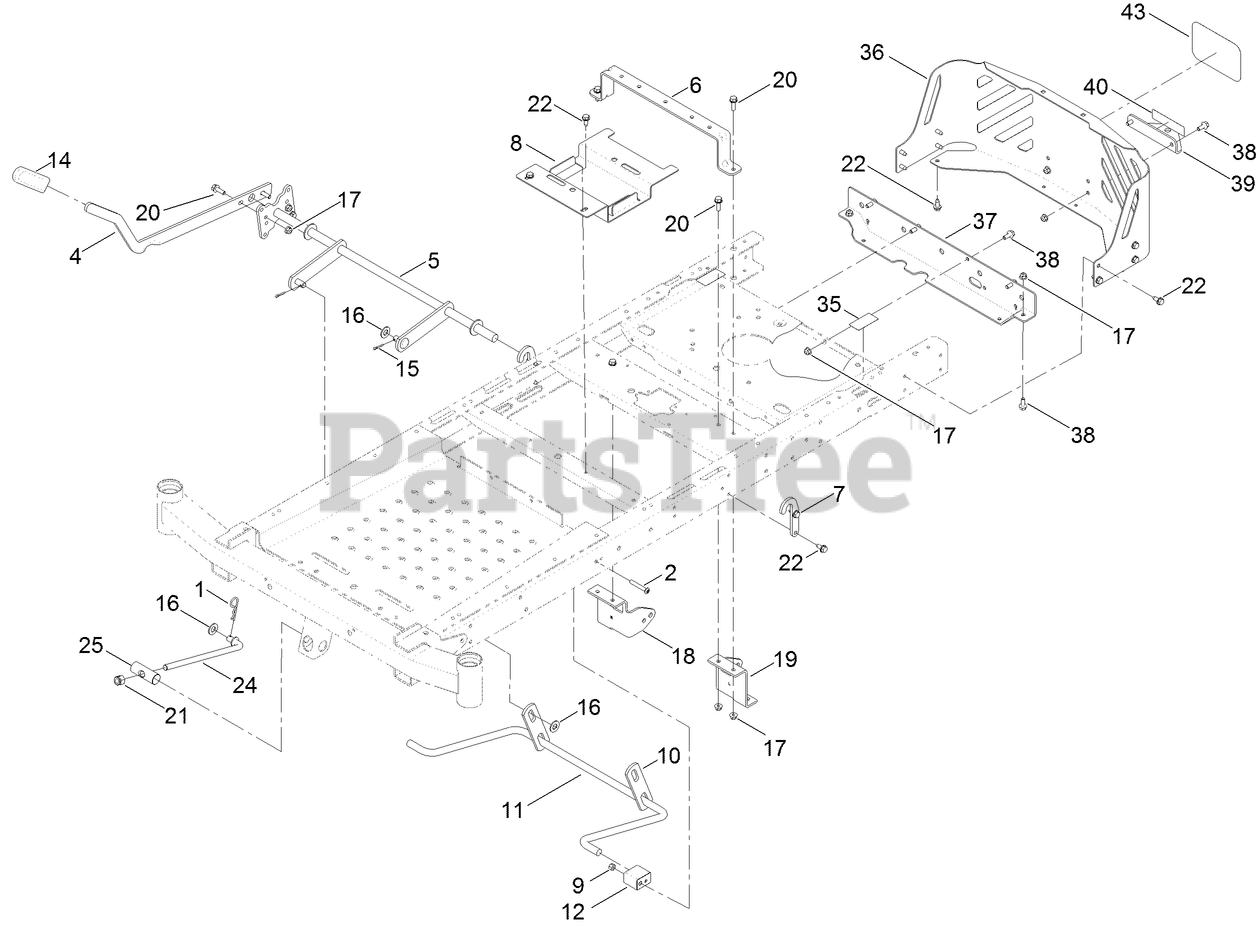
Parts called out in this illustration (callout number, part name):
1	PIN-COTTER
2	SCREW-HSBH
4	LEVER-LIFT
5	LIFT-DECK, WIDE
6	BRACE-SEAT, REAR
7	BRACKET-LIFT
8	BRACKET-BATTERY
9	NUT-LOCK, NI
10	LINK-LIFT
11	ARM-LIFT, REAR (WIDE)
12	BLOCK-PIVOT
14	GRIP-LEVER
15	PIN-COTTER
16	WASHER-FLAT
17	NUT-HF, NI
18	MOUNT-HYDRO, FRONT (RH)
19	MOUNT-HYDRO, FRONT (LH)
20	SCREW-HHF
21	NUT-HEX
22	SCREW-HWHTF
24	ROD-MOUNT, DECK
25	PIN-PIVOT
35	DECAL-BYPASS
36	GUARD-ENGINE, WIDE
37	CROSSMEMBER-REAR, WIDE
38	SCREW-HHF
39	BRACKET-HITCH
43	DECAL
